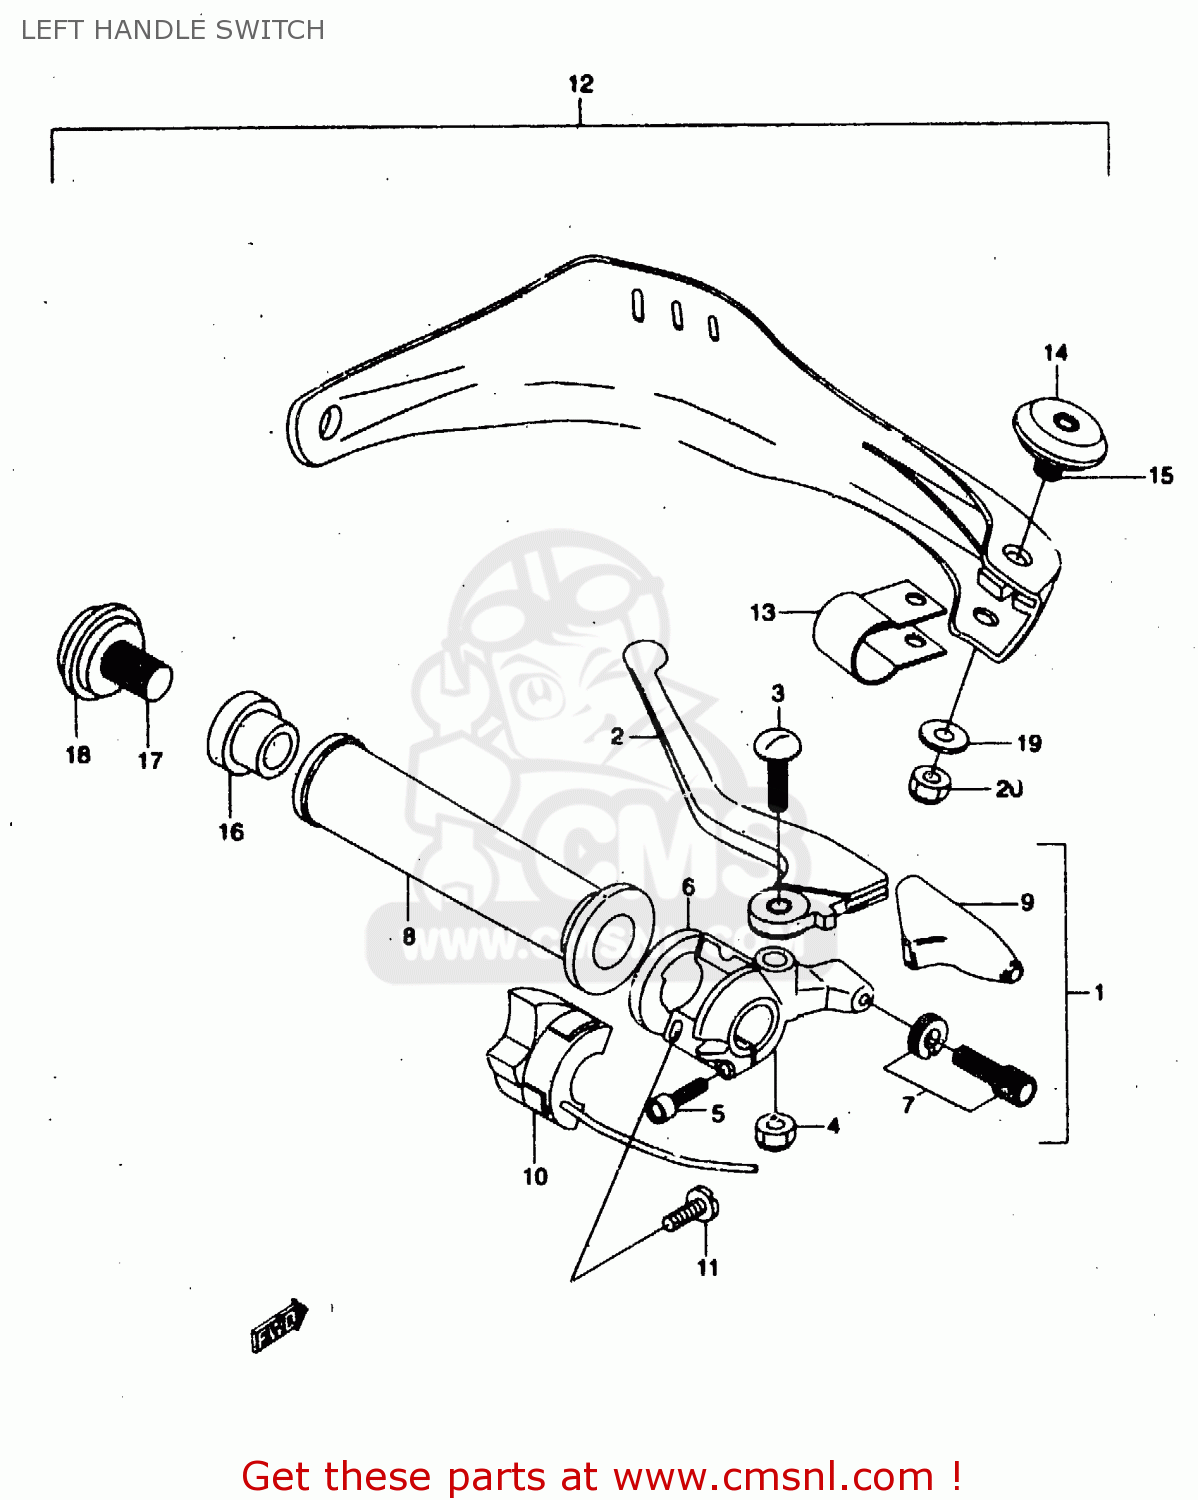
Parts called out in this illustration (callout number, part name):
1	LEVER ASSY, CLUTCH
2	LEVER
3	SCREW
4	NUT 6MM
5	BOLT
6	HOLDER
7	ADJUSTER, CABLE
8	GRIP, LH
9	COVER
10	SWITCH
11	SCREW
12	COVER,KNUCKLE
13	HOLDER
14	SPACER
15	BOLT
16	NUT
17	BOLT
18	SPACER
19	WASHER
20	NUT
